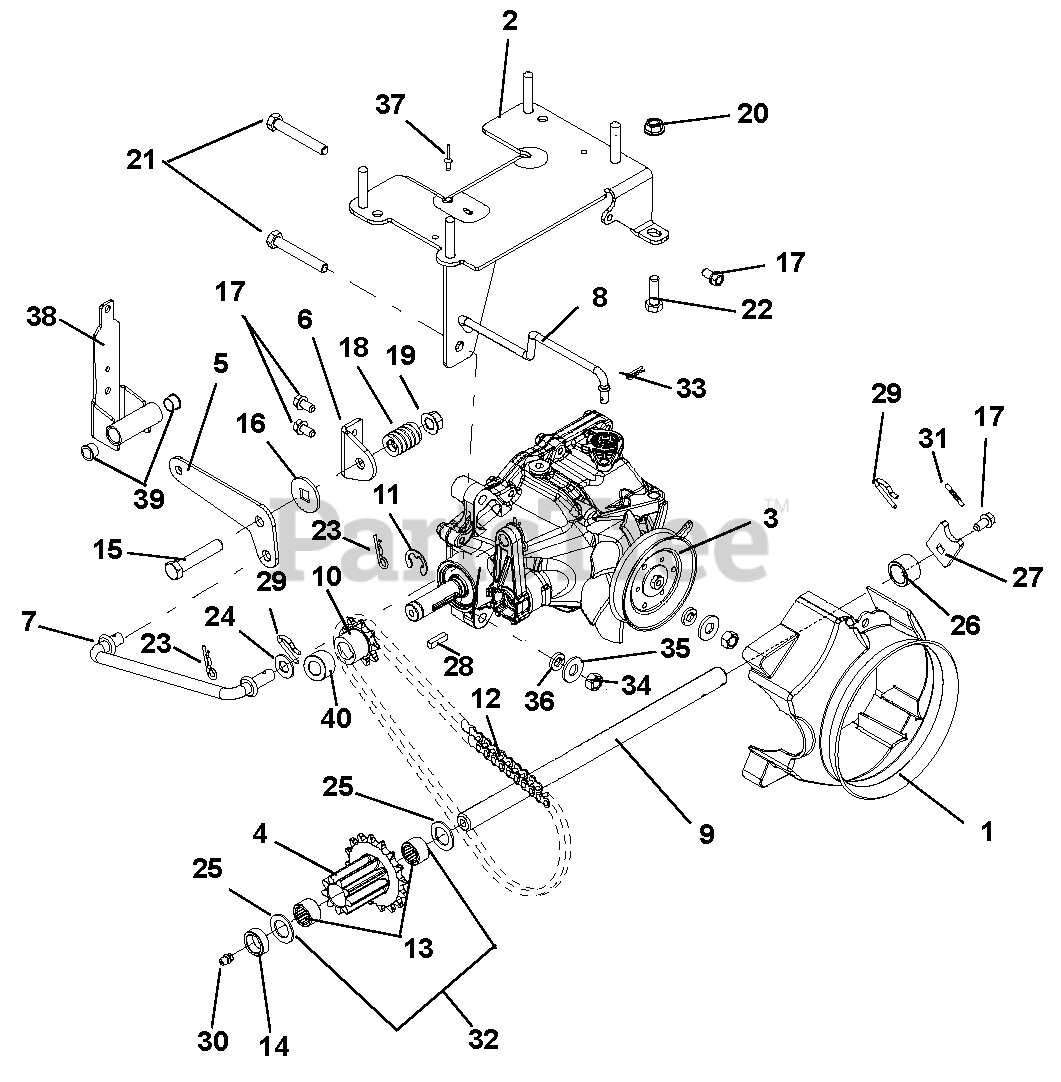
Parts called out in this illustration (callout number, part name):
1	SHROUD, HYDROGEAR RT-310
2	BRACKET, HYDROSTATIC TRANS XLG
3	TRANSMISSION, HYDROSTATIC
4	PINION & SPROCKET
4	PINION & SPROCKET (16T & 9T)
5	PIVOT, HYDRO TRANS SHIFT
6	BRACKET, HYDRO SHIFT PIVOT
7	ROD, HYDRO TRANS SHIFT
8	ROD, HYDRO BYPASS
9	SHAFT, PINION - HARDENED
10	SPROCKET, PINION 9T W/KEY
11	RG-RTNG-EXT .625X.042
12	CHAIN - #41, 32 PITCHES
12	CHAIN-ROLLER #41X26 PITCHES
13	BSHG-FLG .625X.750X.500X.875
13	BRG-NEEDLE .625X.812X.50
14	BSHG-SLV, .635X.880X.305
15	@BLT-HEX .38-16X2.00 GR5 YWZC
16	FRICTION WASHER
17	SCR-TAP .25-20X.50 HWH TR YWZ
18	SG-COMP .187X.56X1.62
19	@NUT-LK-TOP-FLG .38-16 YWZC
20	@NUT-LK-TOP-FLG .31-18 YWZC
21	@BLT-HEX .31-18X2.25 GR5 YWZC
22	@BLT-HEX .31-18X1.00 GR5 YWZC
23	PIN-HAIR INT .08X.18X1.18 YWZC
24	@WSHR-FL-STL.406X.812X.065 YWZ
25	WSHR-FL-STL .630X1.005X.062 YZ
26	SPACER, .635X.880X.611
27	TAB, ANTI ROTATION
28	KEY-SQ .188X.75X.188
29	PIN, SPRING CLIP
30	ZERK,FITTING .25X.125 DRIVE IN
31	@PIN-GRV .125X1.00 TP E ALLOY
32	PINION & SPROCKET W/BUSHINGS
32	PINION & SPROCKET W/BEARINGS
33	PIN-HAIR INT .06X.18X.77
34	@NUT-HEX .31-18 YWZC
35	@WSHR-FL-STL.38X.875X.083 YWZC
36	WSHR-LK .312X.097 HVY YWZC
37	RVT-POP .187 YZ
38	TRANS MOUNT, TENSIONING, WHEEL
38	TRANS MOUNT, TENSIONING, TRACK
39	BSHG-FLG .625X.750X.500X.875
40	SPACER, .635X.880X.611
